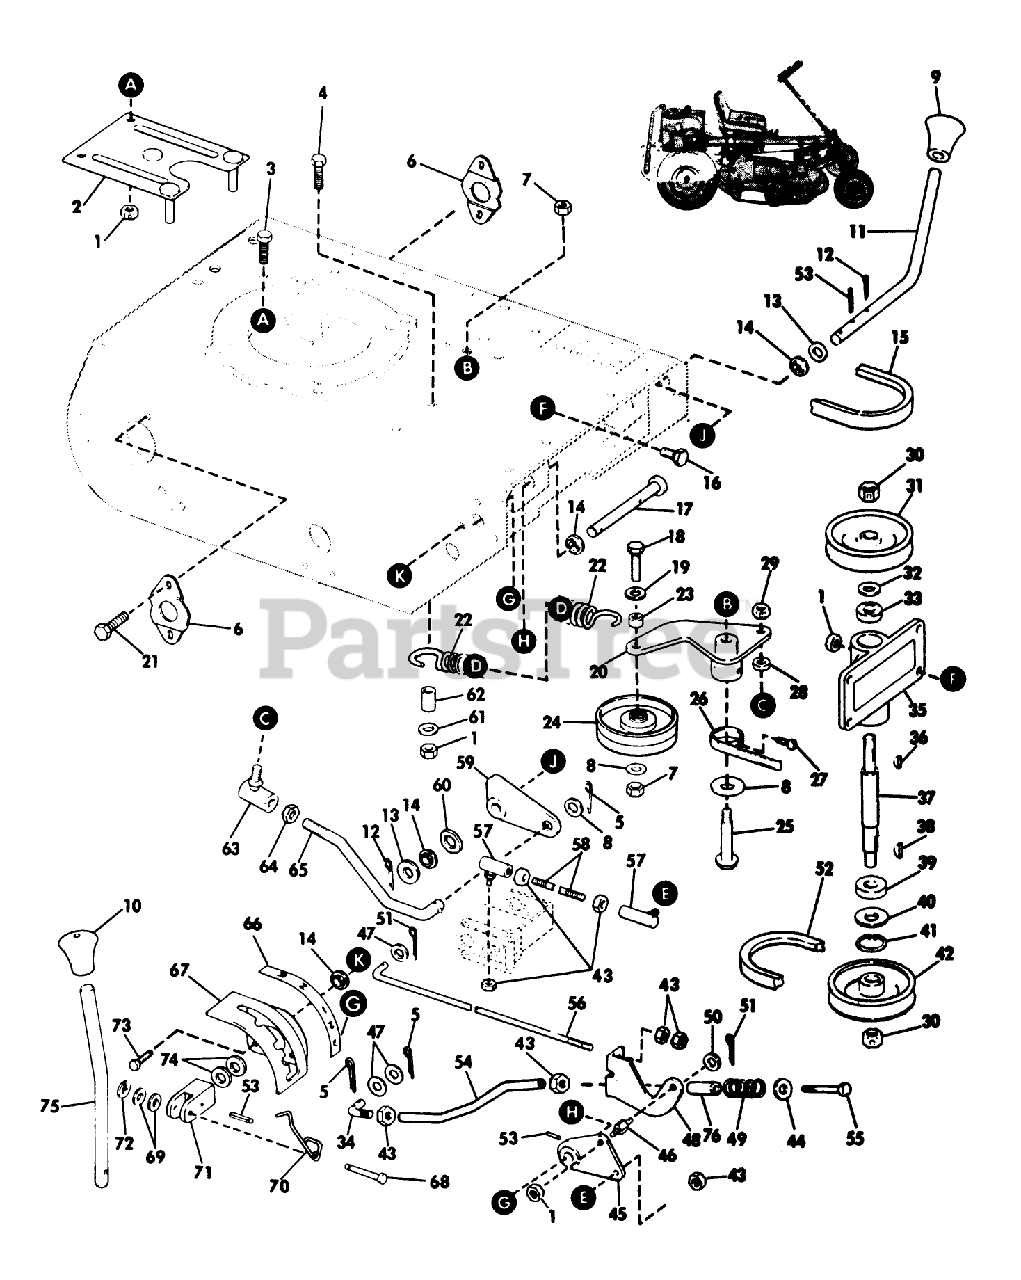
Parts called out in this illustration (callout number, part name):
7	LOCKNUT
12	Cotter Pin
43	STOP NUT
